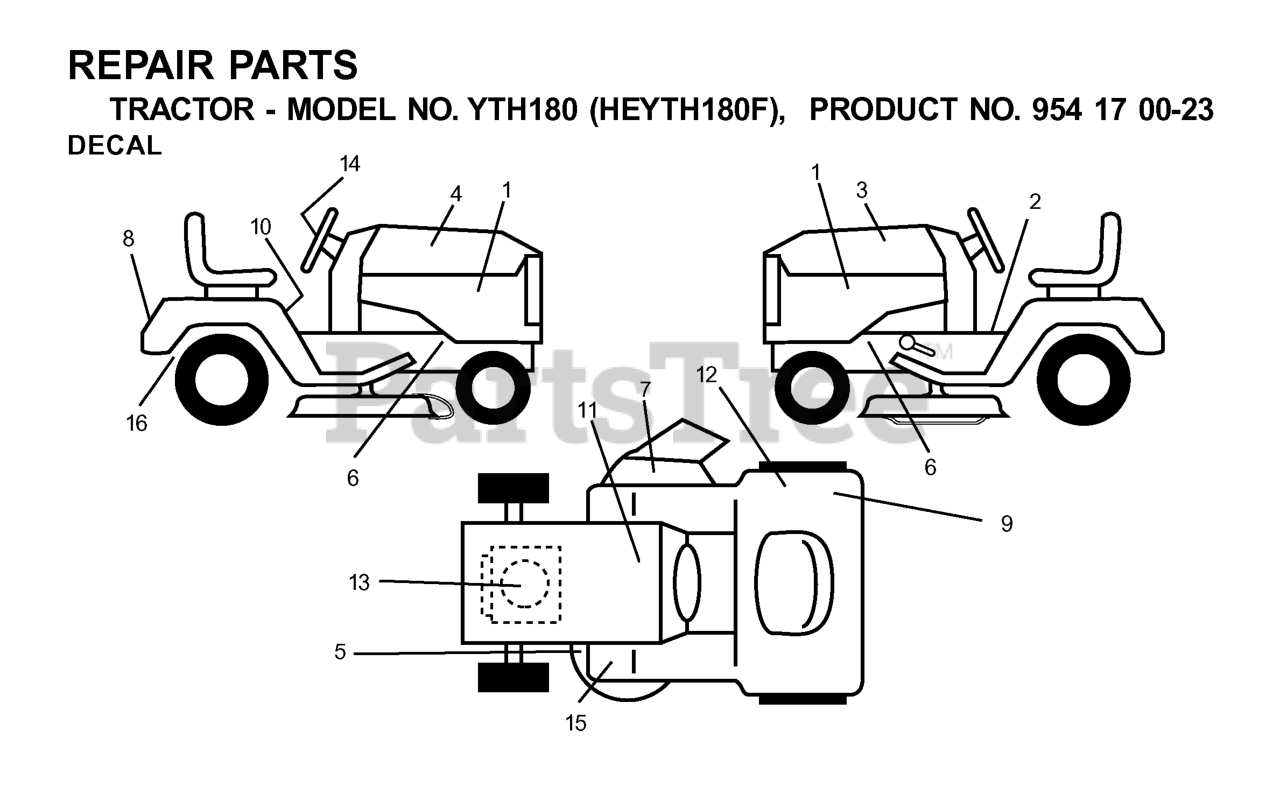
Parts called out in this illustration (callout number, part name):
1	DECAL PNL SIDE
2	DECAL PARK BRAKE
3	DECAL L.H. YTH180
4	DECAL R.H. YTH180
5	DECAL V BELT SCHEMATIC
7	DECAL MOWER CUT/FINGER
8	DECAL FENDER HUSQ
9	DECAL CERTIFICATION
10	DECAL READ OWNER'S MAN SYMS
11	DECAL BTRY SYMBOLS
12	DECAL EUROPE STANDARD CE
14	DECAL.WHEEL.STEERING.HUSQ.PERM
15	DECAL
16	DECAL
